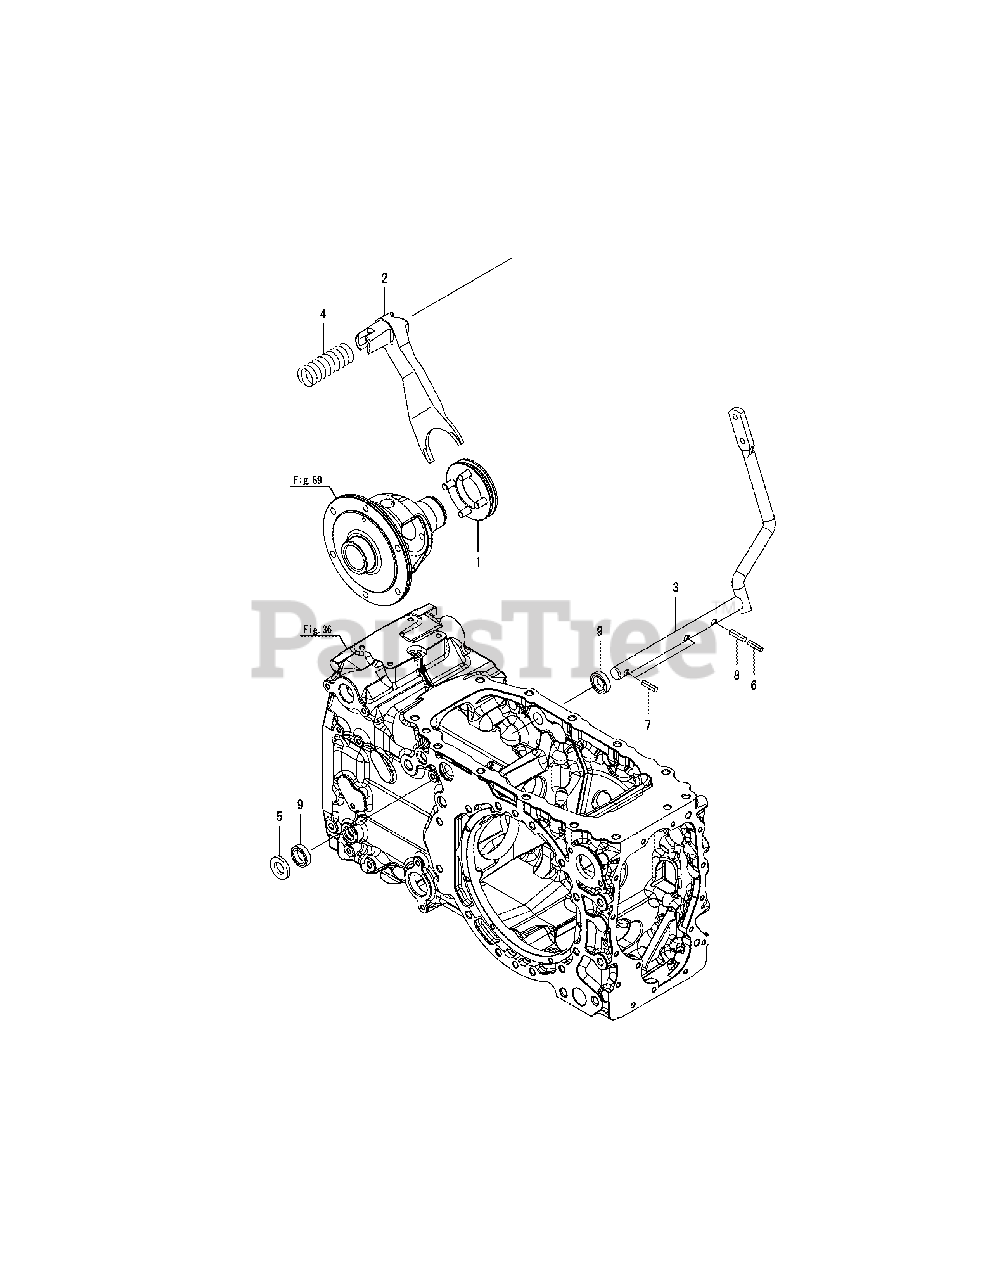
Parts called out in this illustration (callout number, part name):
1	SLIDER, DIFFERENTAL
2	FORK DIFF,SHIFT
3	SHAFT,DIFF LOCK ASSY
4	SPRING, DIFF. LOCK
6	SPRING PIN 5X40
7	SPRING PIN 8X32
8	SPRING PIN 8X40
